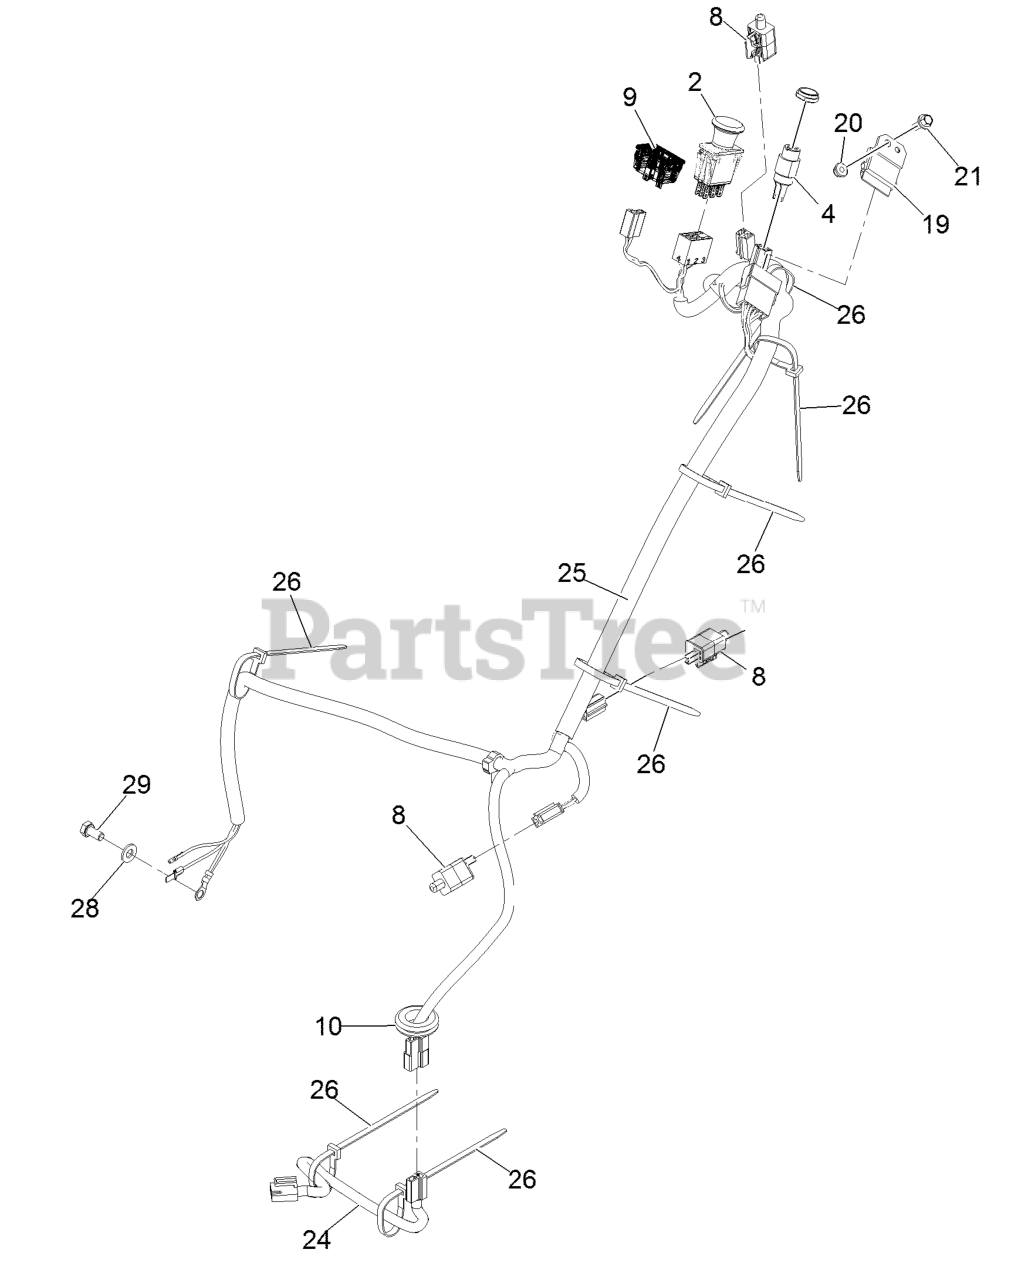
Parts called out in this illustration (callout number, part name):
2	Switch-PTO
4	Switch & Key (Includes Nut & Washer)
4	Nut-Ignition
9	Hour Meter
10	Grommet
19	Module-Interlock
20	Nut-Nyloc 1/4-20 Flg
21	Screw-Head, Flange
24	Harness-Clutch Pigtail
25	Harness-Main
26	Tie-Cable 7 15/16 (Large)
29	Screw-HH M8-1.25 X 16Mm
